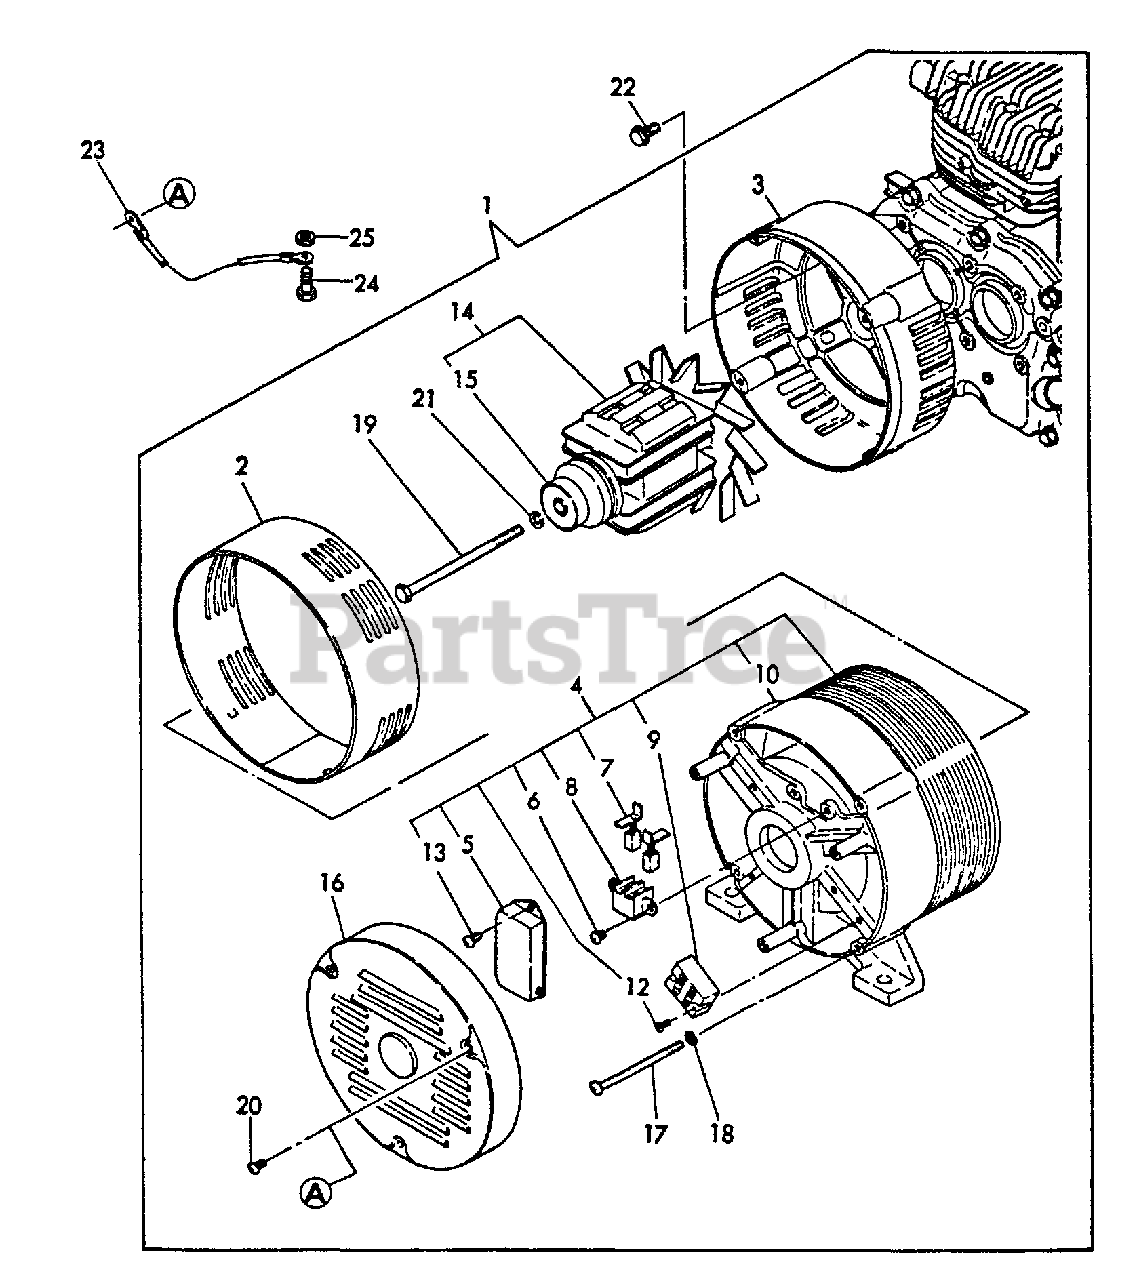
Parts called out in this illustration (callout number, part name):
1	GENERATOR 3.0 KVA
2	CLAMP
3	COVER, FRONT
4	STATOR ASSY
5	A.V.R.
6	SCREW - 5×14
7	BRUSH
8	HOLDER, BRUSH
9	TERMINAL
10	COVER - REAR
12	SCREW - 5×14
13	SCREW - 4×10
14	ROTOR ASSY
15	BEARING, BALL
16	COVER, END
17	BOLT, THROUGH
18	LOCKWASHER - 6
19	BOLT
20	SCREW - 4×10
21	LOCKWASHER - 10
22	BOLT - 8×20 -- PLATED
23	WIRE, EARTH
24	BOLT - 6×16 -- PLATED
25	LOCKNUT - 6 -- PLATED
